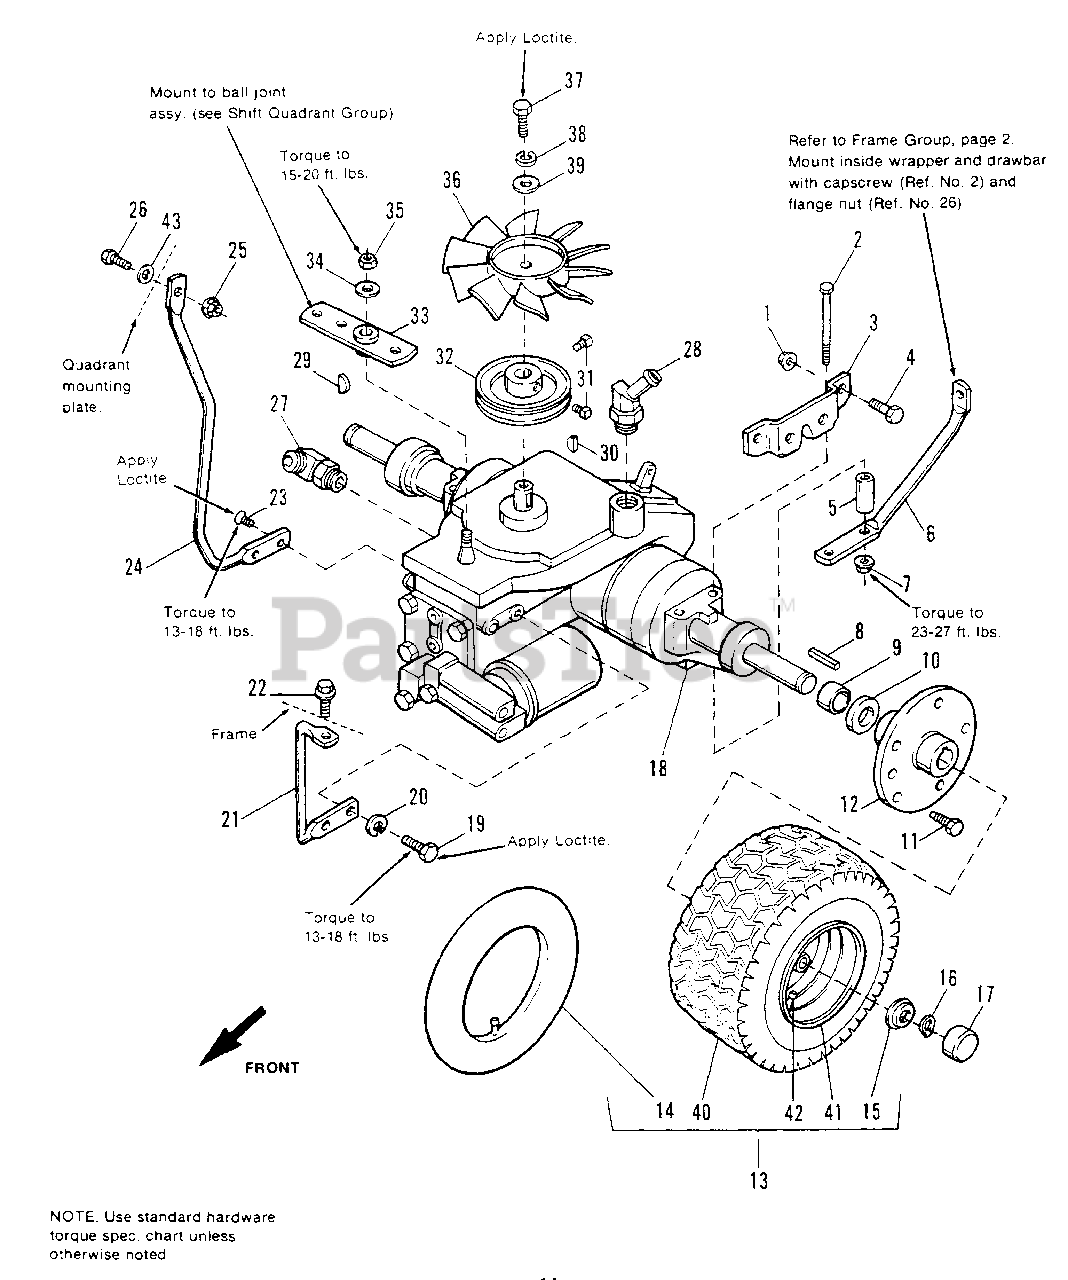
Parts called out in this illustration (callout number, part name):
1	NUT, Hex Flange, Whiz Lock, 3/8-16
2	CAPSCREW, 3/8-16 x 4
3	BRACKET, Transaxle Mounting
4	CAPSCREW, 3/8-16 x 1
5	SPACER, 1-1/4
6	BRACE, Transaxle, Rear, L.H.
7	NUT, Hex, Two-Way Lock, 3/8-16
8	KEY, Straight
9	SPACER, Wheel
11	BOLT, Wheel
12	HUB ASSY., Rear Wheel (Standard)
12	HUB ASSY., Right Rear Wheel 4" Offset used with Electric Lift Kit
13	TIRE & WHEEL ASSY., 23 x 10.50 x 12
15	RETAINER, Hub Cap
16	RING, Retainer
18	TRANSAXLE
19	CAPSCREW, 5/16-18 x 3/4
20	LOCKWASHER
21	TORQUE ARM
22	SCREW, Taptite, 5/16-18 x 5/8
23	SCREW, 5/16-18 x 3/4
24	BRACE, Transaxle, RH
25	NUT, Whiz Flange, 5/16-18
26	CAPSCREW, 5/16-18 x 1
27	FITTING, Hydro
28	FITTING, Hydro
29	KEY, Woodruff (#3)
30	KEY, Hi-Pro
31	SET SCREW, 1/4-28 x 1/2
33	CONTROL ARM ASSY. (Speed)
34	WASHER
35	NUT, Hex, Center-Lock, 3/8-16
36	FAN, 10-Blade (C.C.W.)
37	CAPSCREW, 1/4-20 x 3/4
38	LOCKWASHER
39	WASHER
40	TIRE, 23 x 10.50-12
42	VALVE STEM
